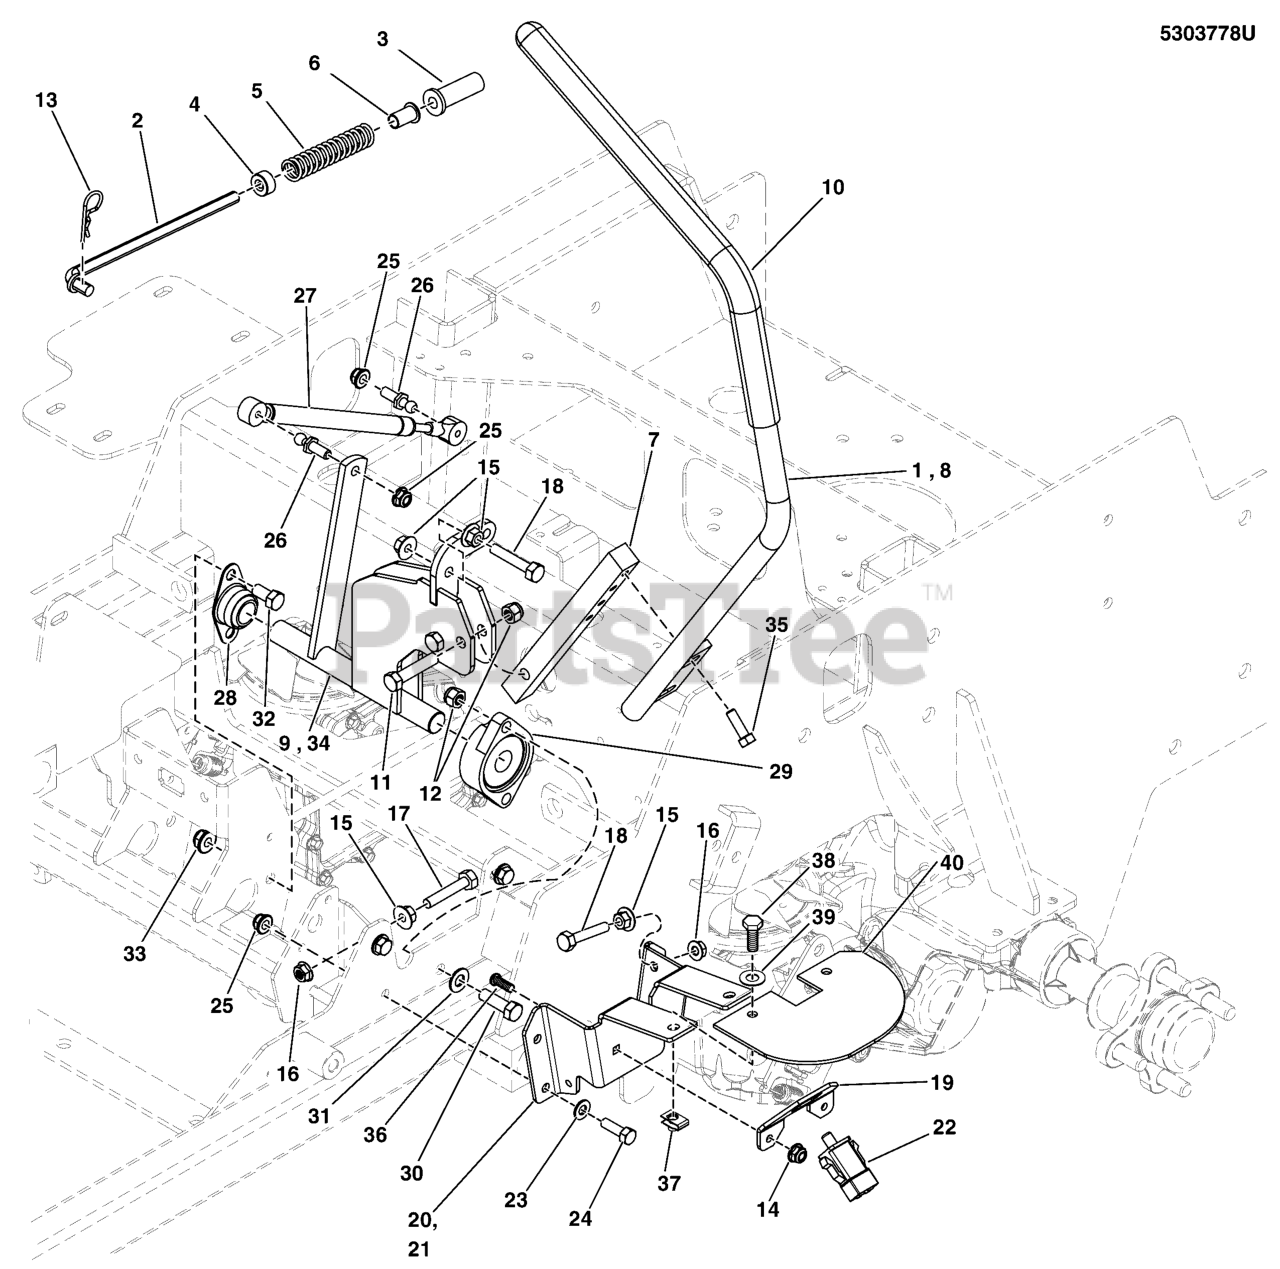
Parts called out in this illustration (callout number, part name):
1	WELD, HANDLE MOTION CONTROL LH - BLK
1	WELD, HANDLE MOTION CNTRL, 19.0, 1.0, LH - BLK
2	ROD, NEUTRAL RETURN, CZ
3	FLANGED BUSHING, 3/8IDX.63ODX.8125FL
4	COLLAR, 3/8" Set
5	SPRING, REVERSE RETURN
6	BUSHING, FLANGE 3/8ID X 7/8 LONG
7	MOUNT, CONTROL ARM - BLK
8	WELD, HANDLE MOTION CONTROL RH - BLK
8	WELD, HANDLE MOTION CNTRL, 19.0, 1.0, RH - BLK
9	WELD, CONTROL SHAFT, RH - BLK
10	GRIP, FOAM, 3/4" ID, 16"" LONG
10	GRIP, FOAM, 1" ID, 16" LONG
11	BOLT, 3/8-16 X 1-3/4" GD5 CZ
12	NUT, 3/8-16 HEX NYLON LOCK
13	3/32 X 1-5/8 HAIR PIN CLIP
14	NUT, 1/4-20 Hex Nylock Flange
15	NUT, 5/16-18 HEX SERRATED FLANGE (LARGE)
16	NUT, 5/16-18 HEX SERRATED FLANGE (SMALL)
17	BOLT- 5/16-18 X 1-1/2 GD5 TFL
18	BOLT, 5/16-18 X 1-3/4 TFL, GD5 YZ
19	BRACKET, SWITCH MOUNT - BLK
20	PLATE, NEUTRAL LOCK, LH - BLK
21	LOCK, Neutral, RH
22	SEE ELECTRICAL GROUP
23	WASHER, 5/16" SAE
24	BOLT, 5/16-18 X 3/4 GD5
25	NUT, 5/16-18 HEX NYLOCK FLANGE NUT
26	10MM BALL STUD, 5/16-18 X 3/4 THDS
27	DAMPENER, CONTROL,#(P6709/P3610)
28	BEARING, BRONZE FLANGE, 3/4"
29	BEARING, FLANGE
30	BOLT, 3/8-16 X 1-1/4" GD5 CZ
31	WASHER, 3/8 SAE
32	BOLT, 3/8-16 X 3/4" GD5 CZ
33	NUT, 3/8 - 16 HEX NYLOCK FLANGE
34	WELD, CONTROL SHAFT, LH - BLK
35	SCREW, 5/16-18x0.750, GR5, WHIZ-LOCK, ZC
36	BOLT,1/4-20X.75,GR5,RH SH SQ NK,ZNC/CLR
37	BODY CLIP, 1/4-20 X 1/2" DEEP
38	BOLT, 1/4"-20 X 3/4" GD5 YZ
39	WASHER, 1/4 SAE
40	PLATE, NEUTRAL LOCK SHIELD - IS700 - BLK
